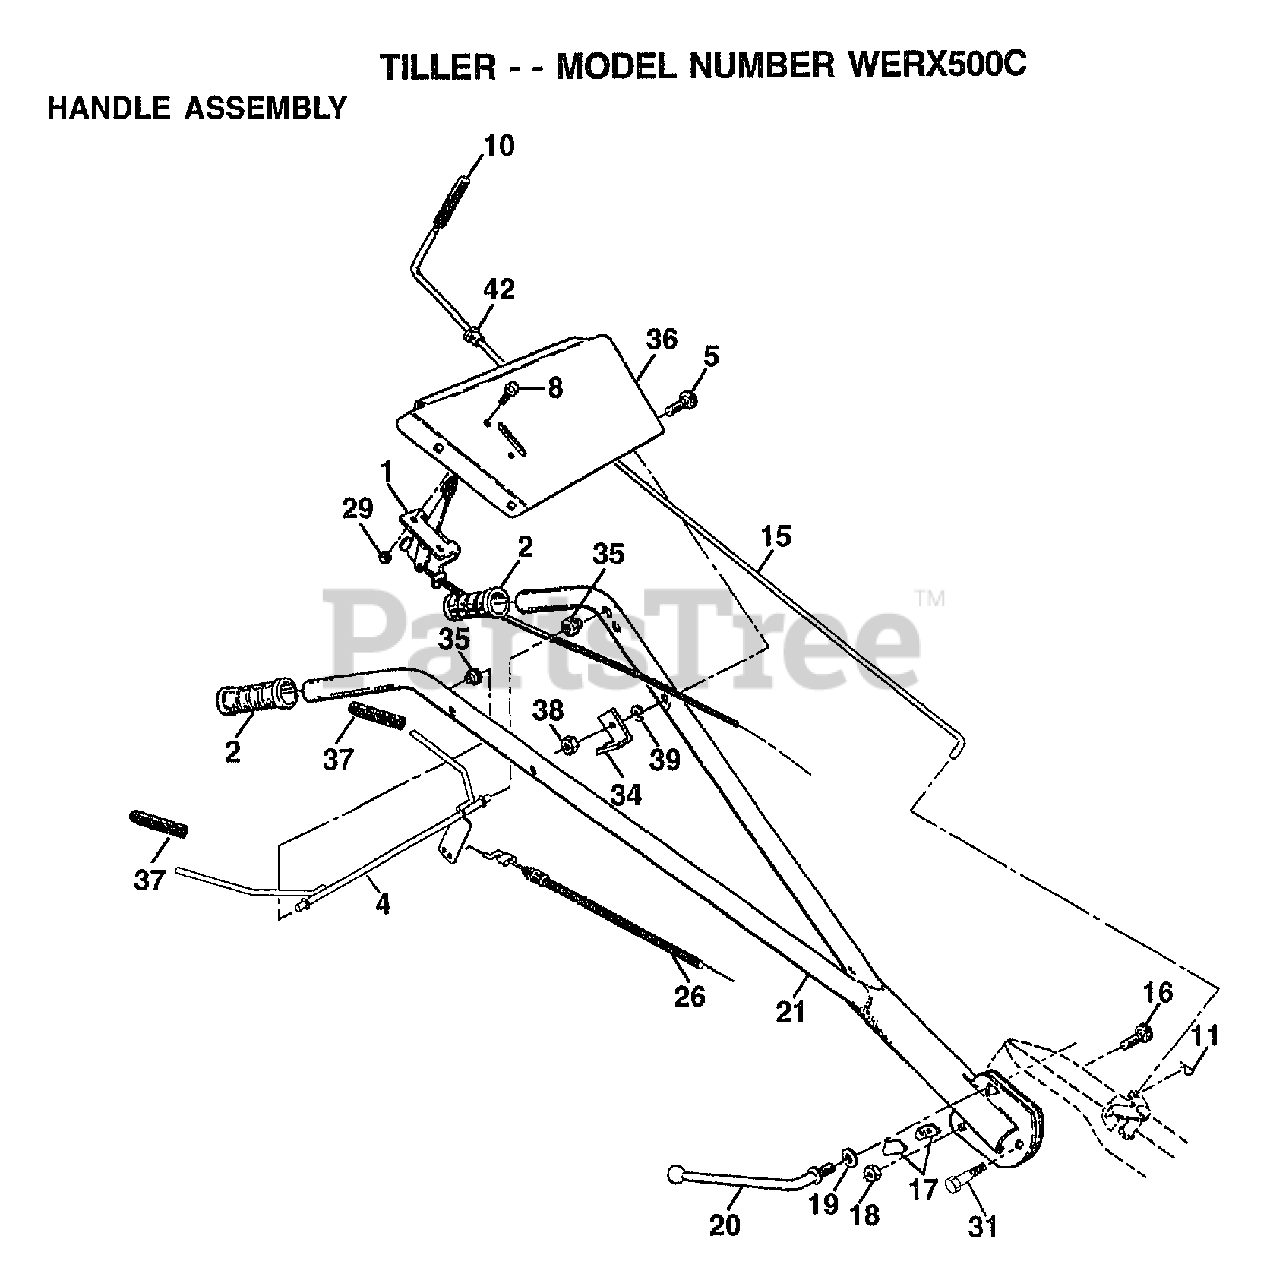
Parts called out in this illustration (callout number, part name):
1	"CONT,THROTTLE"
2	"GRIP,HANDLE"
4	BAR CONTROL
5	BOLT CARRIAGE CRT
8	SCREW.PNHD.10-24
10	GRIP TI
11	RETAINER M
15	ROD SHIFT CRT
16	BOLT D
17	LOCK CRT
19	WASHER CRT
20	LEVER LOCK CRT
26	"CABLE, CLUTCH"
31	BOLT PIVOT
34	BRACKET.CLUTCH.CA
35	GROMMET.HANDLE.V-
36	BRACKET.HDLE.TILL
37	GRIP BAR CRT
38	NUT
39	LOCKWASHER
42	BUSHING
